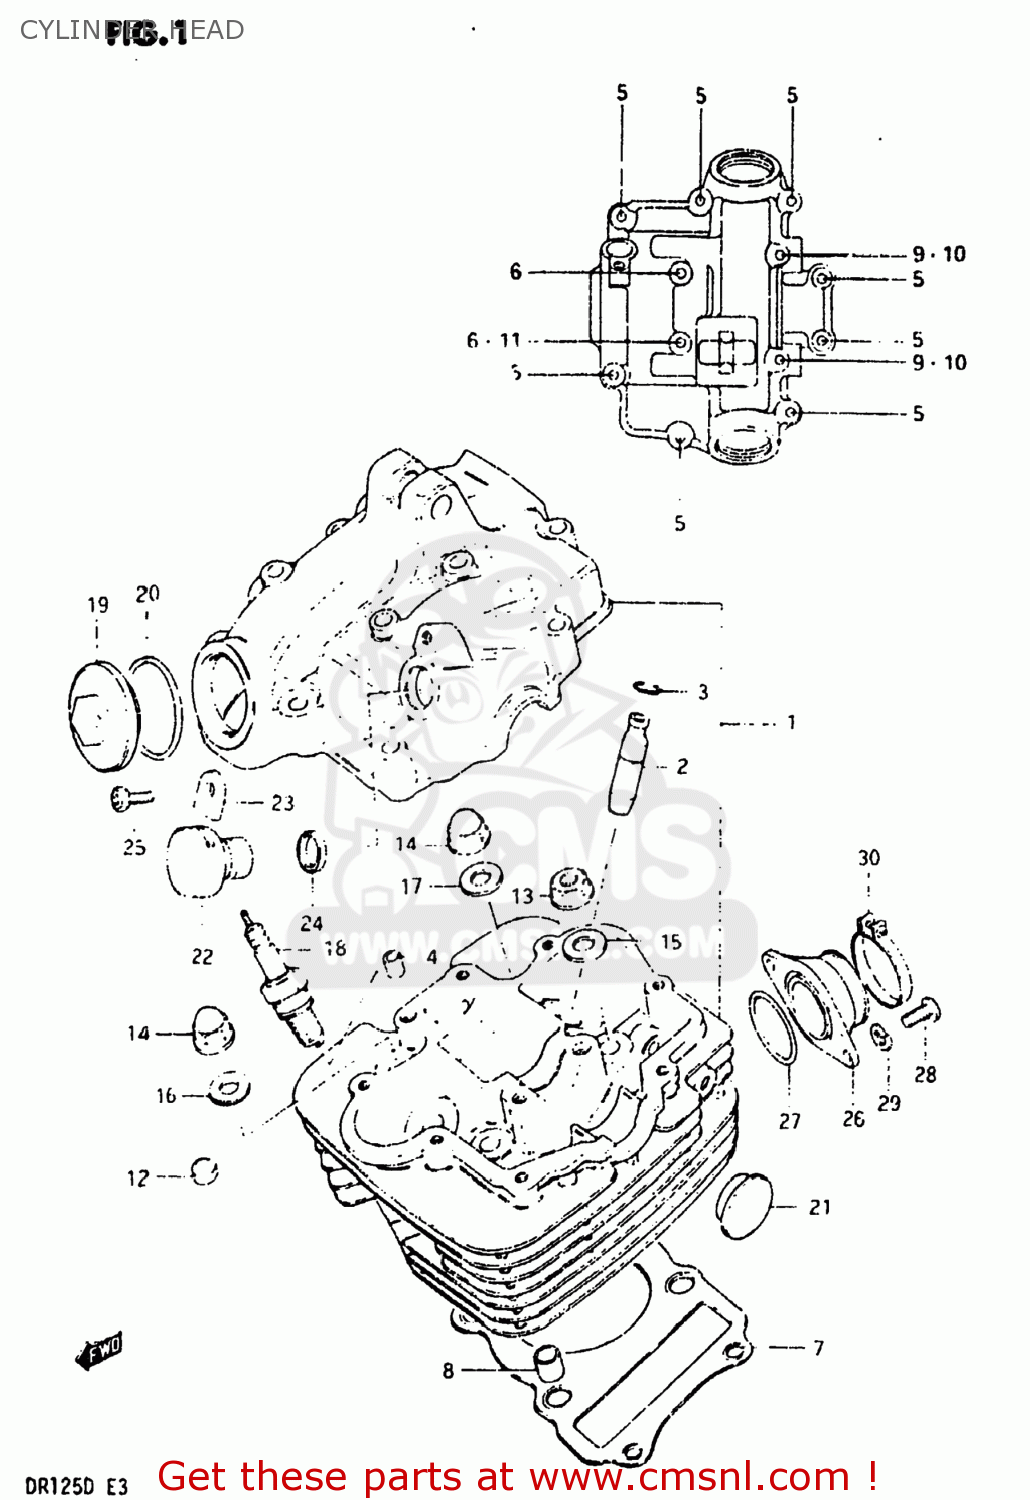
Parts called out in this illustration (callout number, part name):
1	HEAD ASSEMBLY,CYLINDER
2	GUIDE,VALVE
3	RING,SNAP
4	PIN(6.2X8X11)
5	BOLT
6	BOLT ,6X60
7	GASKET,CYLINDER HEAD
8	PIN
9	STUD 6X25
10	NUT
11	GASKET(6.2X11X1).2 (NAS)
12	PAD,CYLINDER HEAD
13	NUT
14	NUT (8MM)
15	WASHER(8.5X19X2.3)
16	WASHER (8.5X19X2.3)
17	GASKET (NAS)
18	SPARK PLUG D8EA
19	CAP,INSPECTION
20	O RING(D:3,ID:29.5)
21	PLUG(OD:22.5)
22	PLUG,TACH GEAR SLEEVE HOLE
23	PLATE,TACH DRIVE GEAR SLEEVE
24	SEAL,TACHOMETER DRIVEN
25	SCREW(5X12)
26	PIPE,INTAKE
27	O RING(D:2.4,ID:31.7)
28	SCREW
29	LOCK WASHER
30	CLAMP
